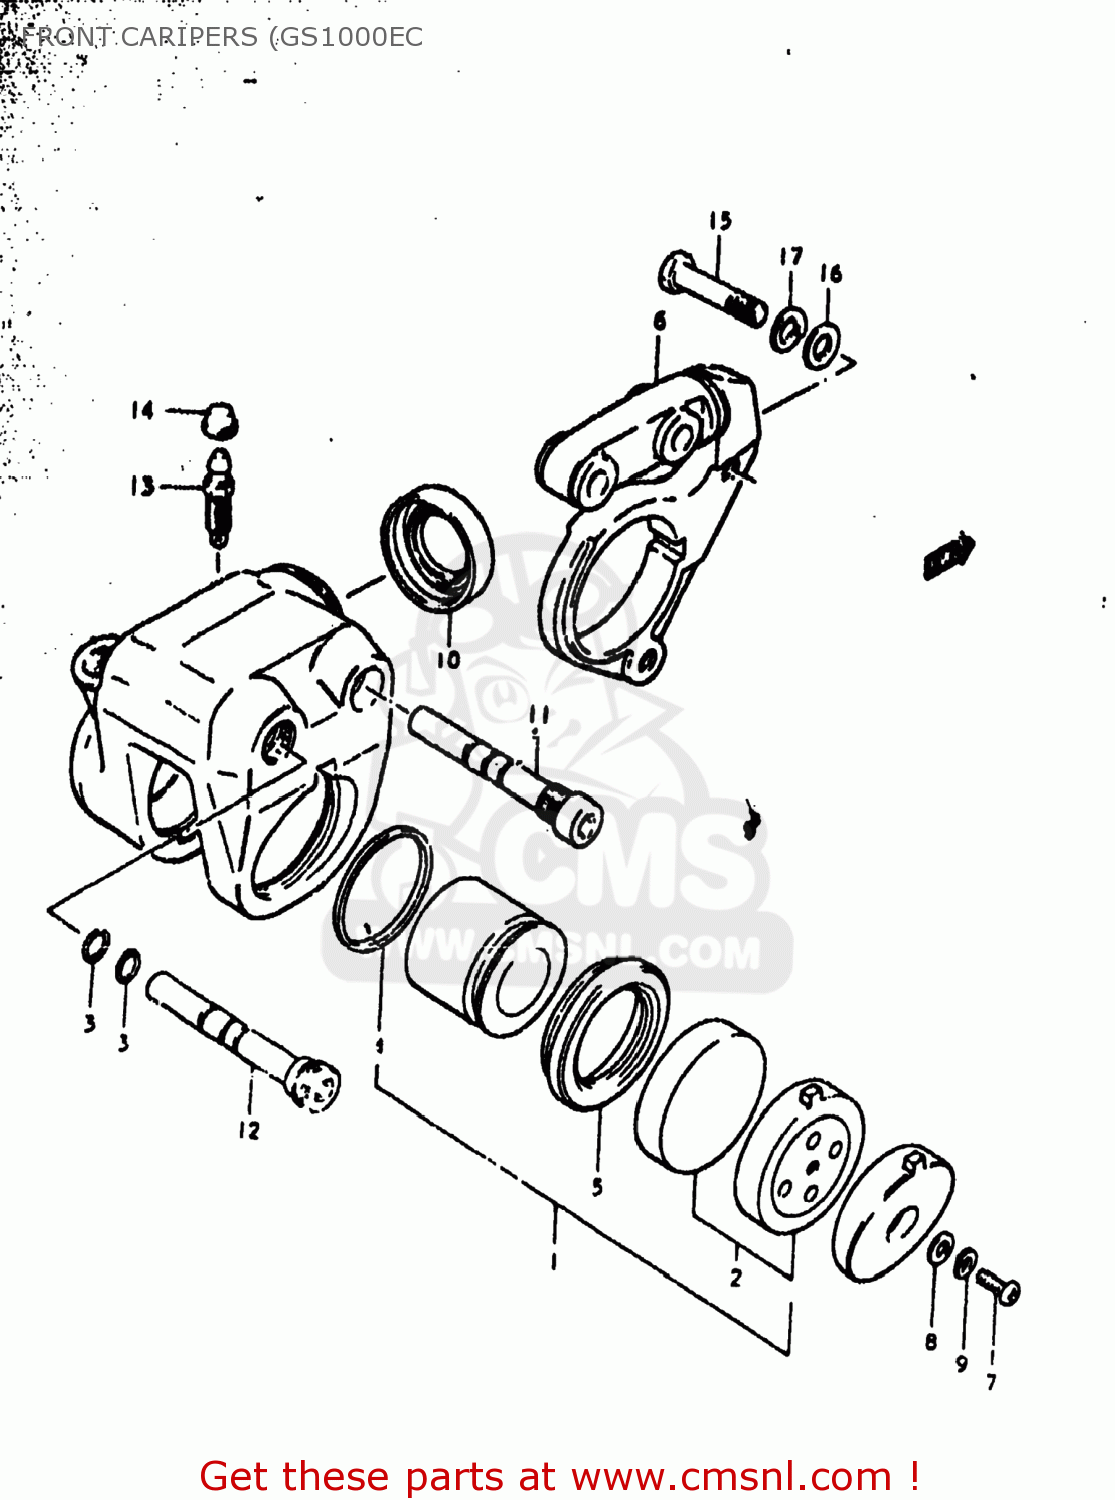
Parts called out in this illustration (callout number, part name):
0	CALIPERS ASSY, RH
1	PISTON & PAD SET
2	PAD SET (MCA)
3	O RING,AXLE CALIPER
4	SEAL,PISTON
5	BOOT,PISTON
6	HOLDER,CALIPER
7	SCREW
8	WASHER
9	LOCK WASHER
10	BOOT,HOLDER
11	AXLE,CALIPER
12	AXLE NO.2
13	BLEEDER
14	CAP,BLEEDER PL
15	BOLT
16	WASHER
17	LOCK WASHER
